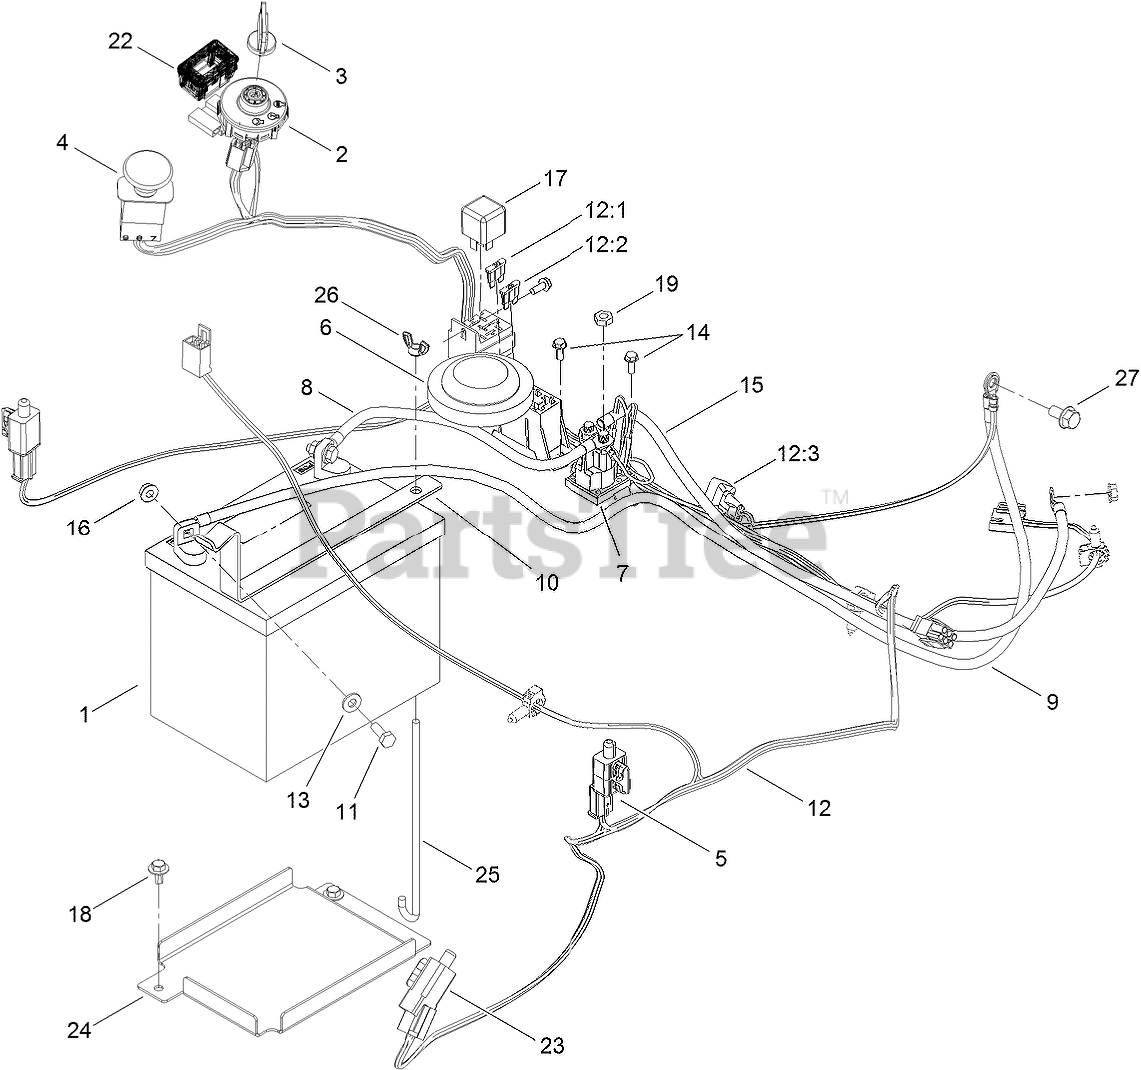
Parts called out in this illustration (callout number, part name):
1	BATTERY
2	SWITCH-IGNITION
3	KEY-IGNITION
4	SWITCH-PTO
5	SWITCH
6	SWITCH-SEAT
7	SOLENOID
8	CABLE-BATTERY, POSITIVE
9	CABLE-BATTERY, NEGATIVE
10	STRAP-BATTERY
11	SCREW-HH
12	Harness-Wire
12:1	FUSE-BLADE, 30 AMP
12:2	FUSE-BLADE, 25 AMP
13	WASHER-FLAT
14	SCREW-TAPTITE
15	WIRE-21 INCH
16	NUT-HF
17	RELAY
18	SCREW-HHFTF
19	NUT-JAM
22	HOURMETER
23	SWITCH-REVERSE
24	TRAY-BATTERY
25	BOLT-HOLDDOWN
26	WINGNUT
27	SCREW-HHF
